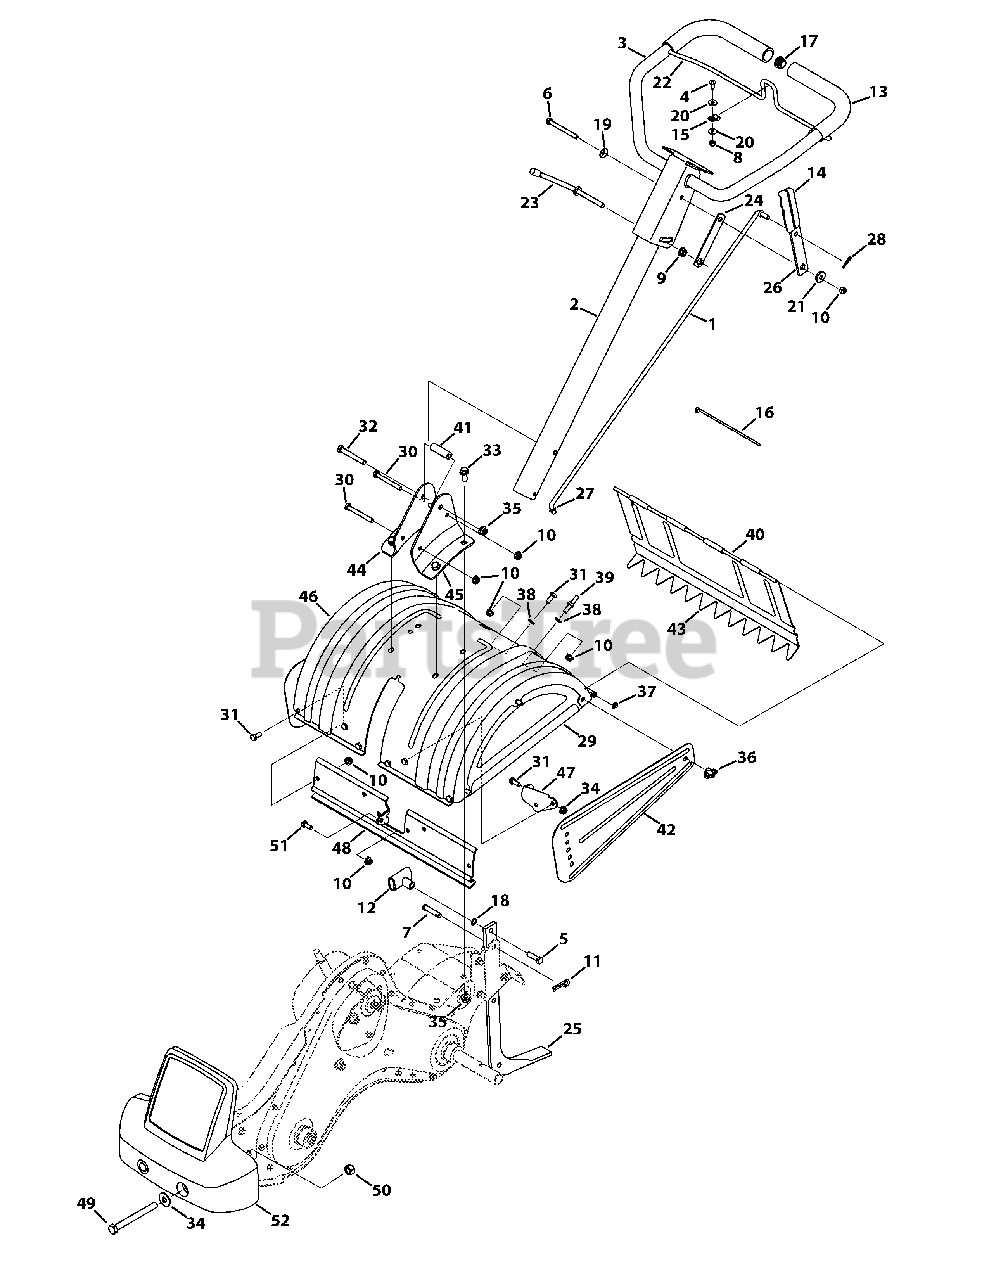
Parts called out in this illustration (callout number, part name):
1	Shift Rod
2	Lower Handle Tube Assembly
3	Upper Handle Assembly
4	Screw, 1/4-20 x 0.625
5	Hex Head Screw, 3/8-16:1.25
6	Hex Head Screw, 5/16-18 x 3.25
7	Clevis Pin, .375 X 1.75
8	Flange Lock Nut, 1/4-20
9	Flange Lock Nut, 3/8-24
10	Flange Lock Nut, 5/16-18
11	Cotter Pin
12	Small Tee Knob
13	Foam Grip, .970 x 11.0
14	Grip, .1875 x 1.00
15	Battery Clamp, 5/16
16	Cable Tie, 8.5 LG
17	End Plug
18	Washer, Flat, .385 x .620 x .033
19	Washer, Bell, .340 x .872 x .060
20	Washer, Flat, .260 x .720 x .060
21	Spacer, .50 x .190 x .360 LG
22	Clutch Bail
23	Handle Adjustment Crank
24	Hex Nut Retainer Bracket
25	Tiller Depth Control
26	Shaft Rod Lever
27	Washer, .33 ID x .87 OD x .125
28	Cotter Pin, .072 x 1.12 LG
29	End Cover Assembly
30	Hex Head Screw, 5/16-18 x 2.75
31	Hex Head Screw, 5/16-18 x .75
32	Hex Head Screw, 3/8-16 x 2.75
33	Hex Head Flange, 3/8-16 x .875
34	Flat Washer, 1/2 x 1.25 x .10
35	Flange Lock Nut, 3/8-16
36	Wing Nut, 5/16-18 w/ Bell Washer
37	Speed Nut Cap, 1/4 ROD
38	Washer, Flat, .344 x .62 x .033
39	Screw, Hex, 5/16-18 x .75
40	Tiller Flap Rod
41	Spacer, .322 x .625 x 2.00
42	Side Shield
43	Rear Tine Shield
44	RH Handle Mount Bracket
45	LH Handle Mount Bracket
46	Tine Shield
47	FRT Tine Shield Bracket
48	FRT Tine Shield Spacer Bracket
49	Hex Head Screw, 1/2-20 x 5.50
50	Flange Lock Nut, 1/2-13
51	Hex Screw, 5/16-18 x 1.00
52	Counterweight
